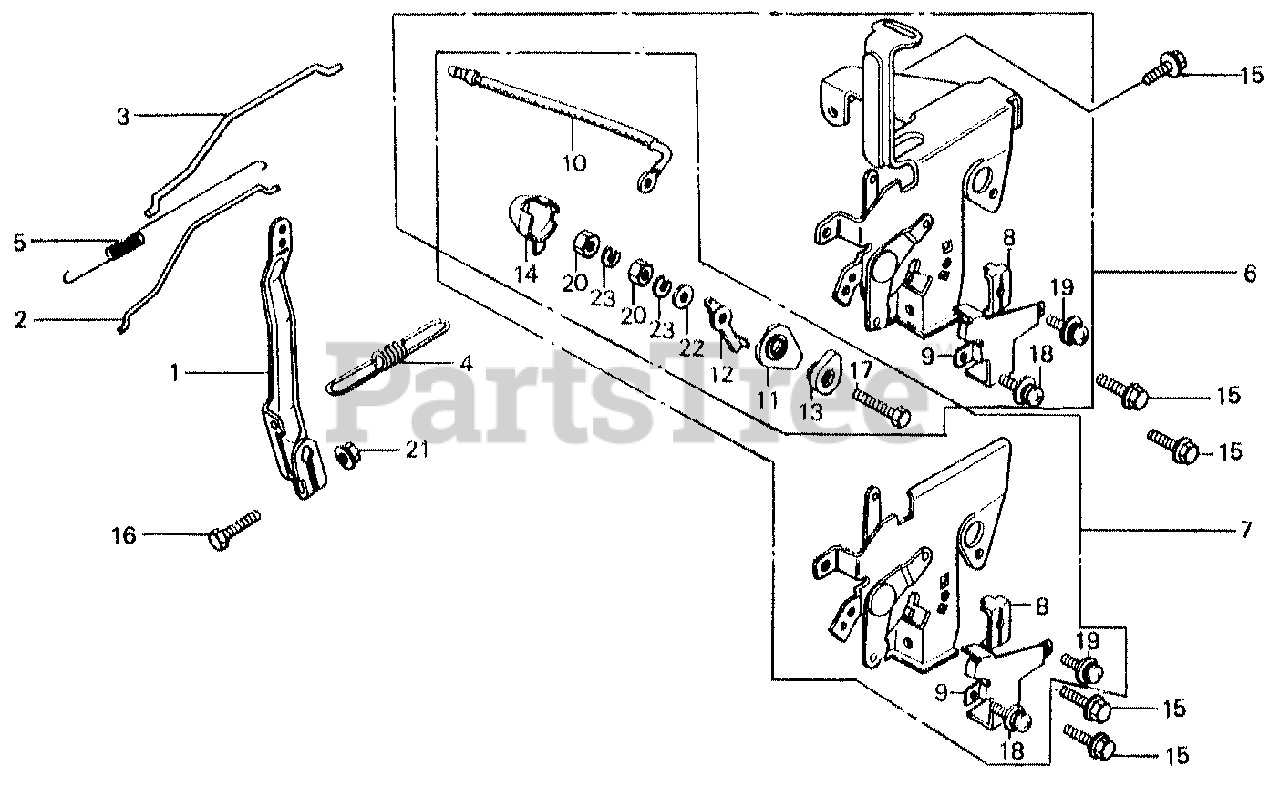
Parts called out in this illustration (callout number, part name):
1	ARM, GOVERNOR
2	ROD, GOVERNOR
3	ROD, CHOKE
4	SPRING, GOVERNOR (NOT AVAILABLE)
5	SPRING, THROTTLE RETURN
7	CONTROL ASSY.
8	HOLDER, CABLE
9	PROTECTOR, CONTROL
10	WIRE, STOP SWITCH
11	BASE, SWITCH
12	CONTACT, SWITCH
13	WASHER, INSULATOR
14	CAP, STOP SWITCH
15	BOLT, FLANGE (6X12) (CT200)
16	BOLT, GOVERNOR ARM
16	BOLT, HEX. (6X20)
17	BOLT, HEX. (4X20)
18	SCREW-WASHER (5X12)
19	SCREW-WASHER (5X20) (NOT AVAILABLE)
20	NUT, HEX. (4MM)
21	NUT, FLANGE (6MM)
22	WASHER, PLAIN (4MM)
23	WASHER, SPRING (4MM)
